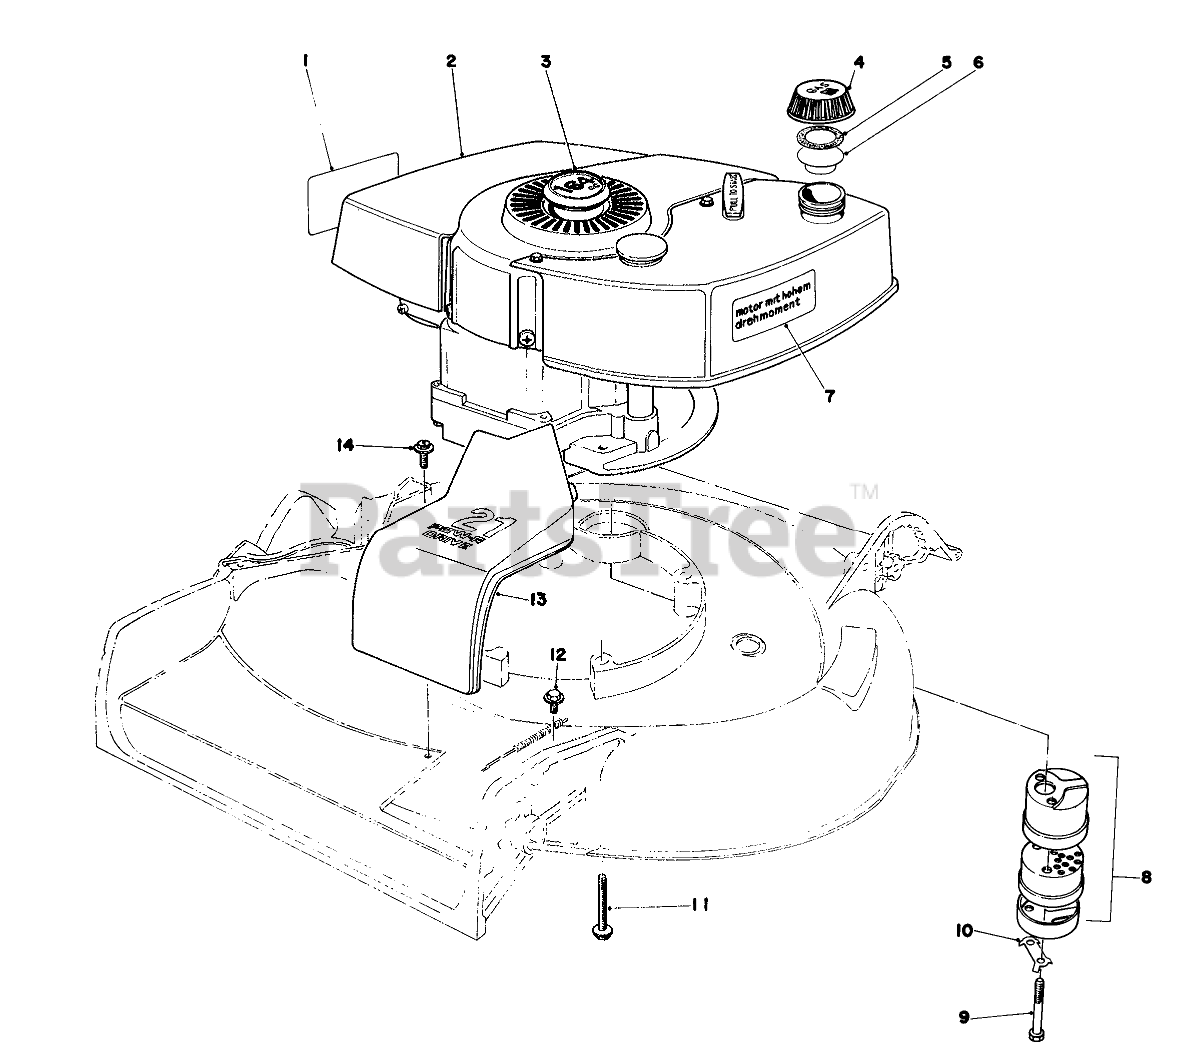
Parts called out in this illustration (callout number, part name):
1	Decal-Maintenance
2	Engine
3	Plug Button
4	Gas Cap (Incl. Ref. #5 & 6)
5	GASKET
6	GAS CAP BAFFLE
7	Decal-High Torque
8	MUFFLER ASM
9	SCREW-HH
10	CLIP - LOCKING
11	3/8-16 X 2-3/4 CAPSCR
12	SCREW-HWHTF
13	BELT DRIVE COVER
14	SCREW
